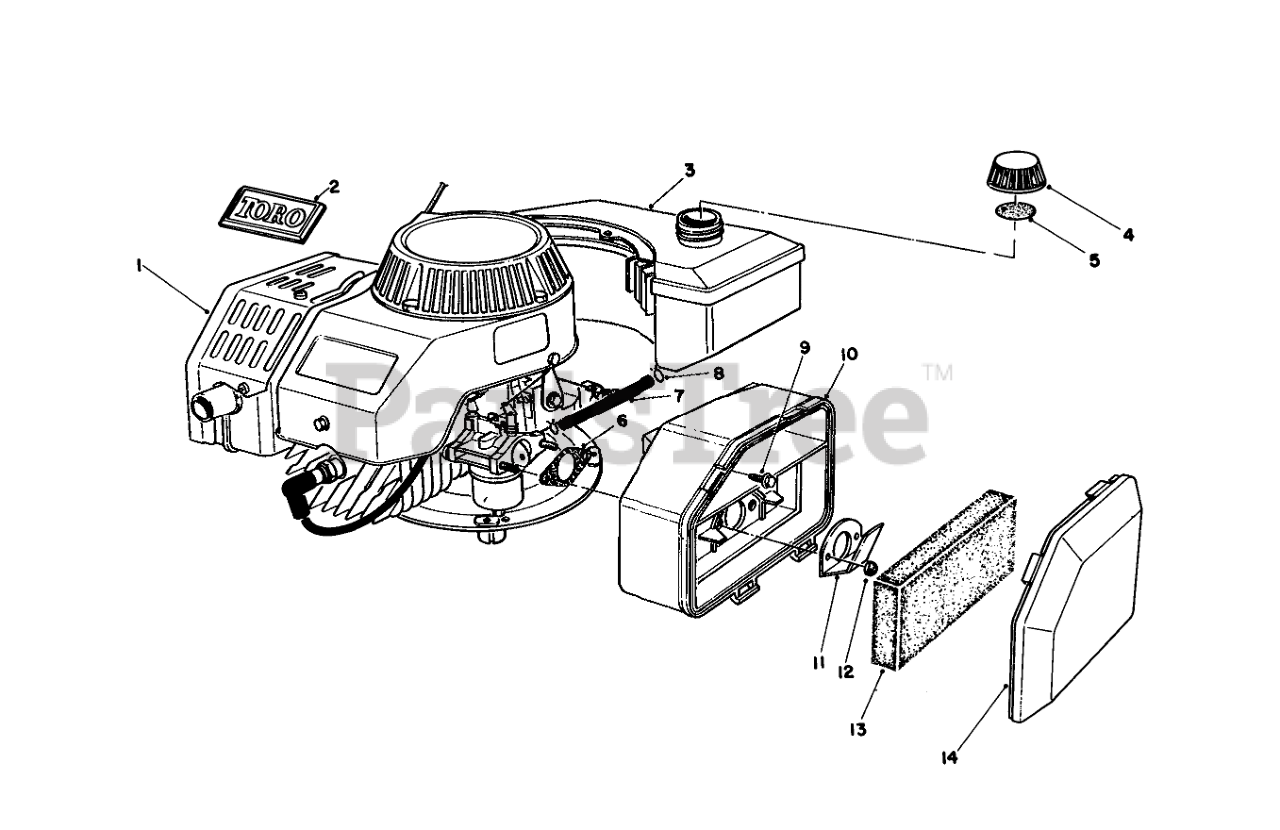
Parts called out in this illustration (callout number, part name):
1	Engine
2	TORO LOGO PLT
3	Gas Tank Assembly
4	Gas Cap Assembly (Incl. Ref. #5)
5	GAS CAP GASKET
6	GASKET-AIR CLEANER
7	FUEL LINE
8	CLAMP-HOSE
9	HEX FL HD M.6X1.0X25MM
10	AIR CLEANER
11	SPIT BACK DEFLECTOR
12	NUT-LOCK
13	FILTER
14	AIR CLEANER COVER
